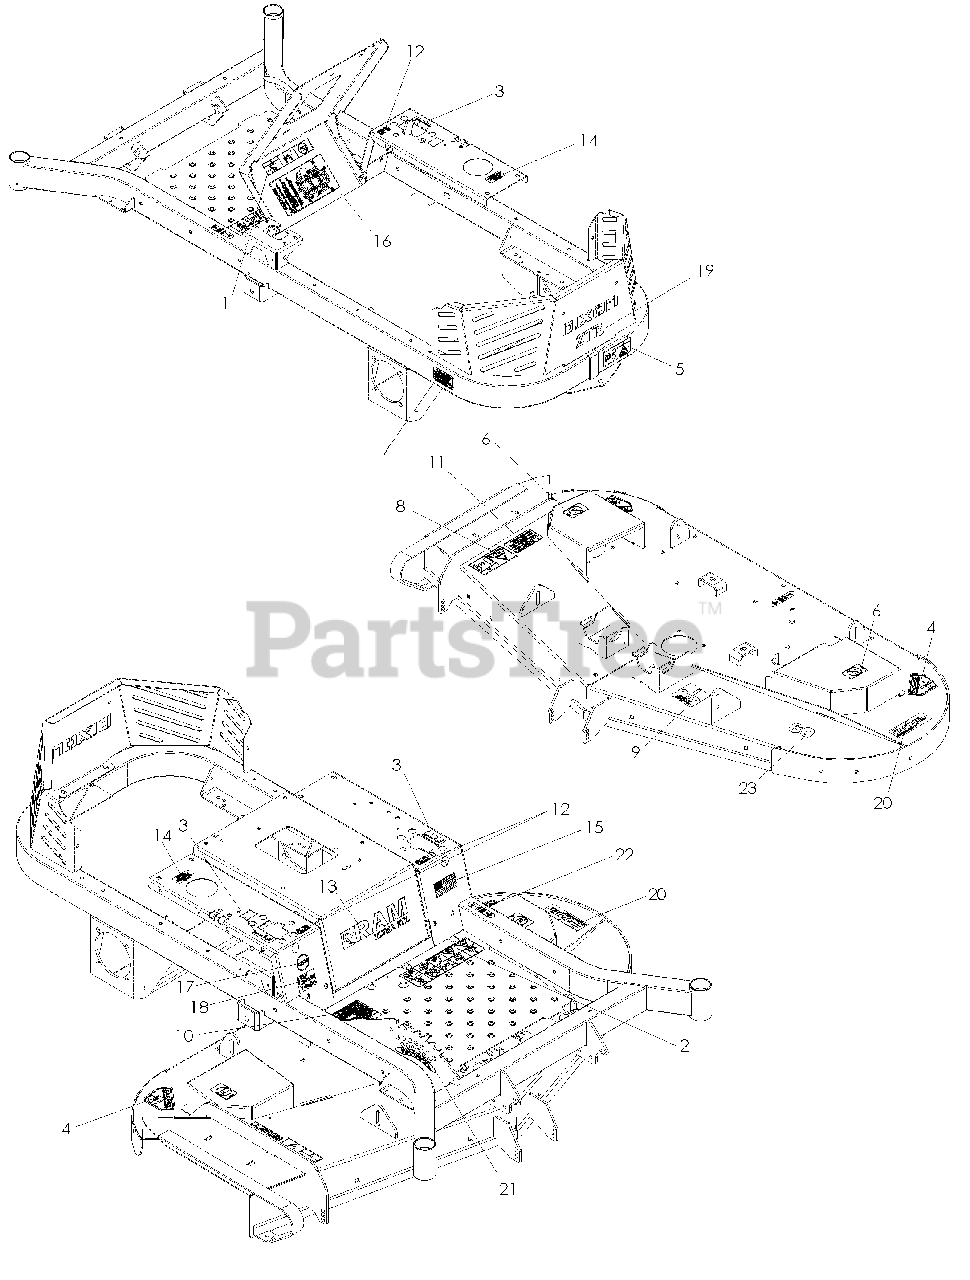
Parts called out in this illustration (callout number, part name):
1	DECAL, BATTERY
2	DECAL, WARNING
3	DECAL, MOTION CONTROL
4	DECAL, CPSC
5	DECAL, BELT DRIVE
6	DECAL, NO STEP
7	DECAL, PROP. 65
8	DECAL, EURO SEVERING
9	DECAL, BELT ROUTING (18656)
10	DECAL, WARNING
11	DECAL, CAUTION
12	DECAL, F.S.T.
13	DECAL, RAM ULTRA
14	DECAL, OIL TANK
15	DECAL, FLAG
16	DECAL, SERVICE
17	DECAL, KOHLER
18	DECAL, PARKER
19	DECAL, ZTR
20	DECAL, FUSION
21	DECAL, HEIGHT ADJUSTMENT
22	DECAL, PARK BRAKE
23	DECAL, DECK 50"
23	DECAL, 60"
23	DECAL, 72"
